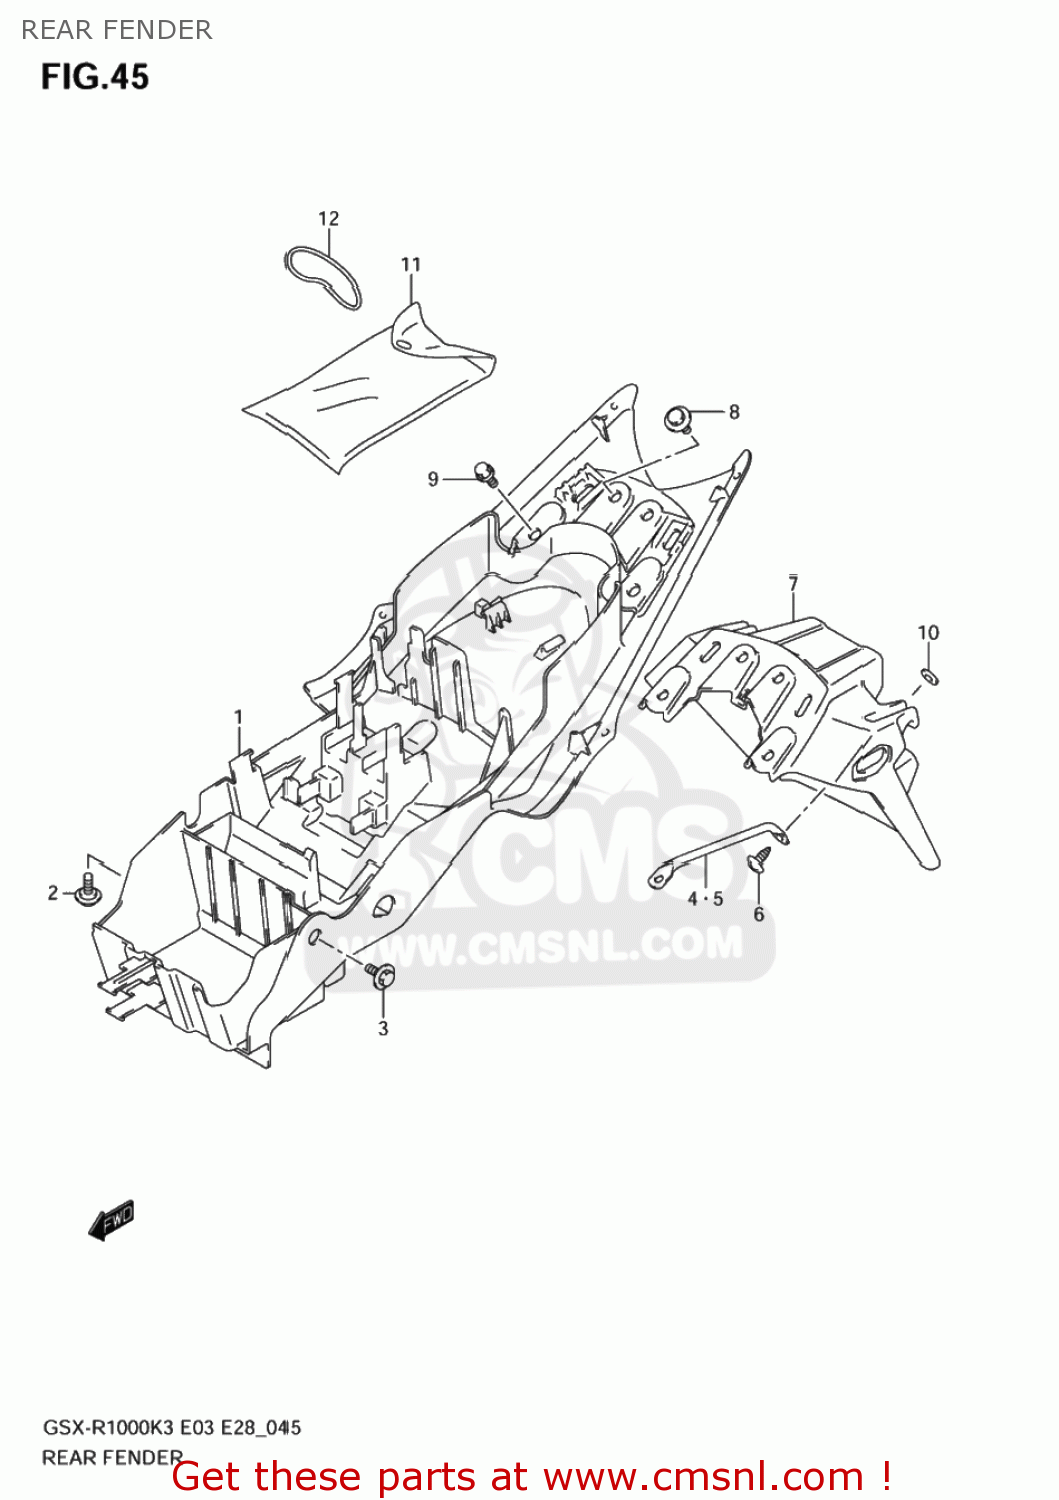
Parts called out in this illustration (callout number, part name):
1	FENDER,RR FR
2	BOLT(6X18)
3	BOLT(6X16)
4	REINF,REAR FEN
5	REINF,REAR FEN
6	SCREW
7	FENDER,RR RR
8	BOLT(6X16)
9	BOLT
10	WASHER
11	TOOL ASSY
12	O RING(D:3.5,ID:61)
